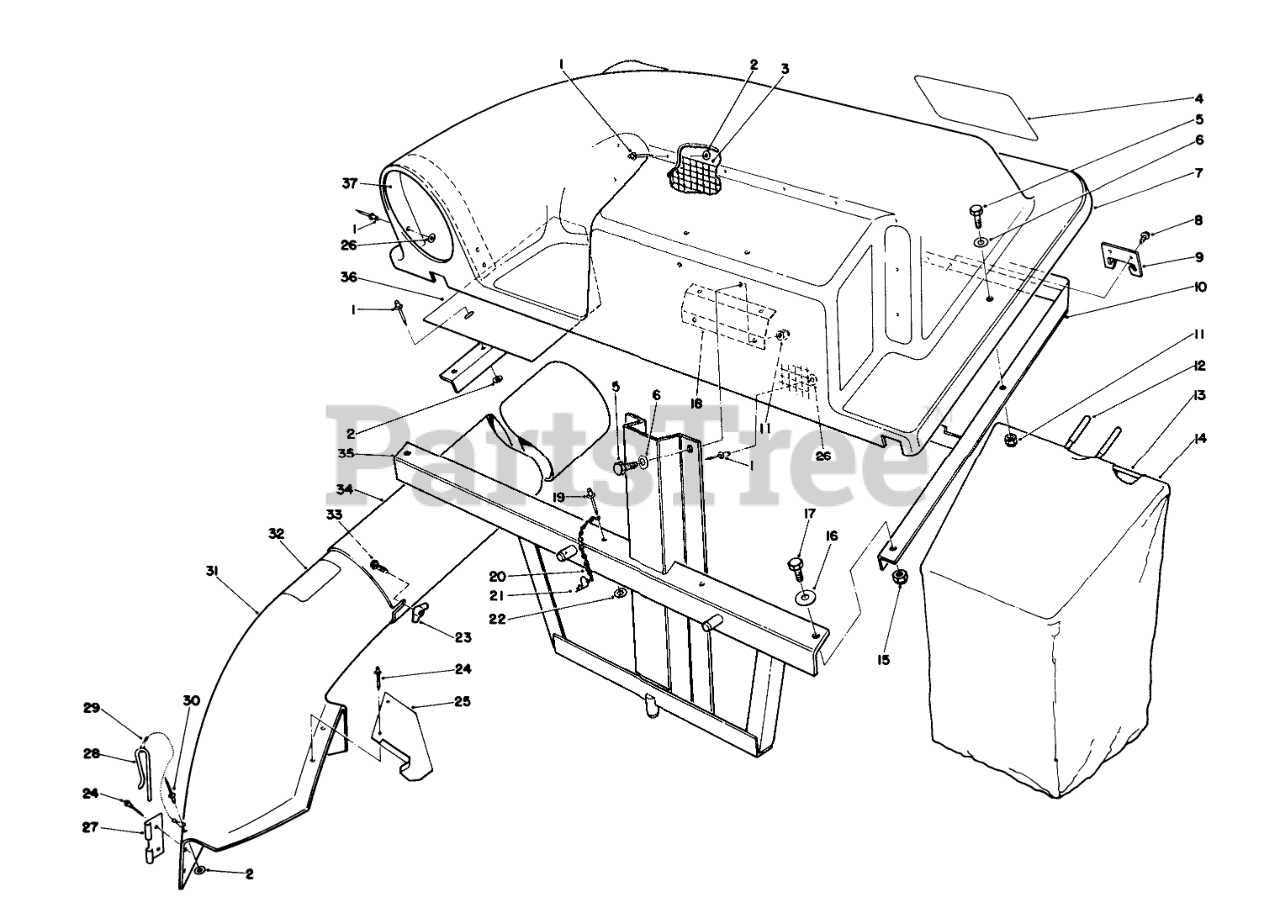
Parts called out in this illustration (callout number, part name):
1	RIVET-POP
2	WASHER-PLAIN
3	SCREEN
4	DECAL-BAGGER, TWIN
5	SCREW-HH
6	WASHER-PLAIN
7	COVER-BAGGER, TWIN
8	SCREW-HWH
9	BRACKET-FRAME, BAG
10	Cover-Frame
11	NUT-LOCK, NI
12	GRIP-HANDLE, BAG
13	Frame-Bag
15	NUT-LOCK, NI
16	WASHER-FLAT
17	SCREW-HH
18	Plate-Backup
20	10 LINK CHAIN W/O HOOK
21	PIN-HAIR
22	WASHER-BACK
23	NUT-WING SPECL
24	RIVET-BLIND
25	CHUTE SUPT BRKT
26	WASHER-FLAT
27	BRACKET-MOUNTING, CHUTE
28	PIN-LOCKING, CHUTE
29	LANYARD
30	RIVET-BLIND
31	Chute Assembly (Incl. Ref. #24-30 & 32)
32	DECAL-DANGER
33	BOLT-CARR
34	TUBE(ROUND&LONG)
35	Frame-Mounting
36	Baffle
37	Support Inlet
